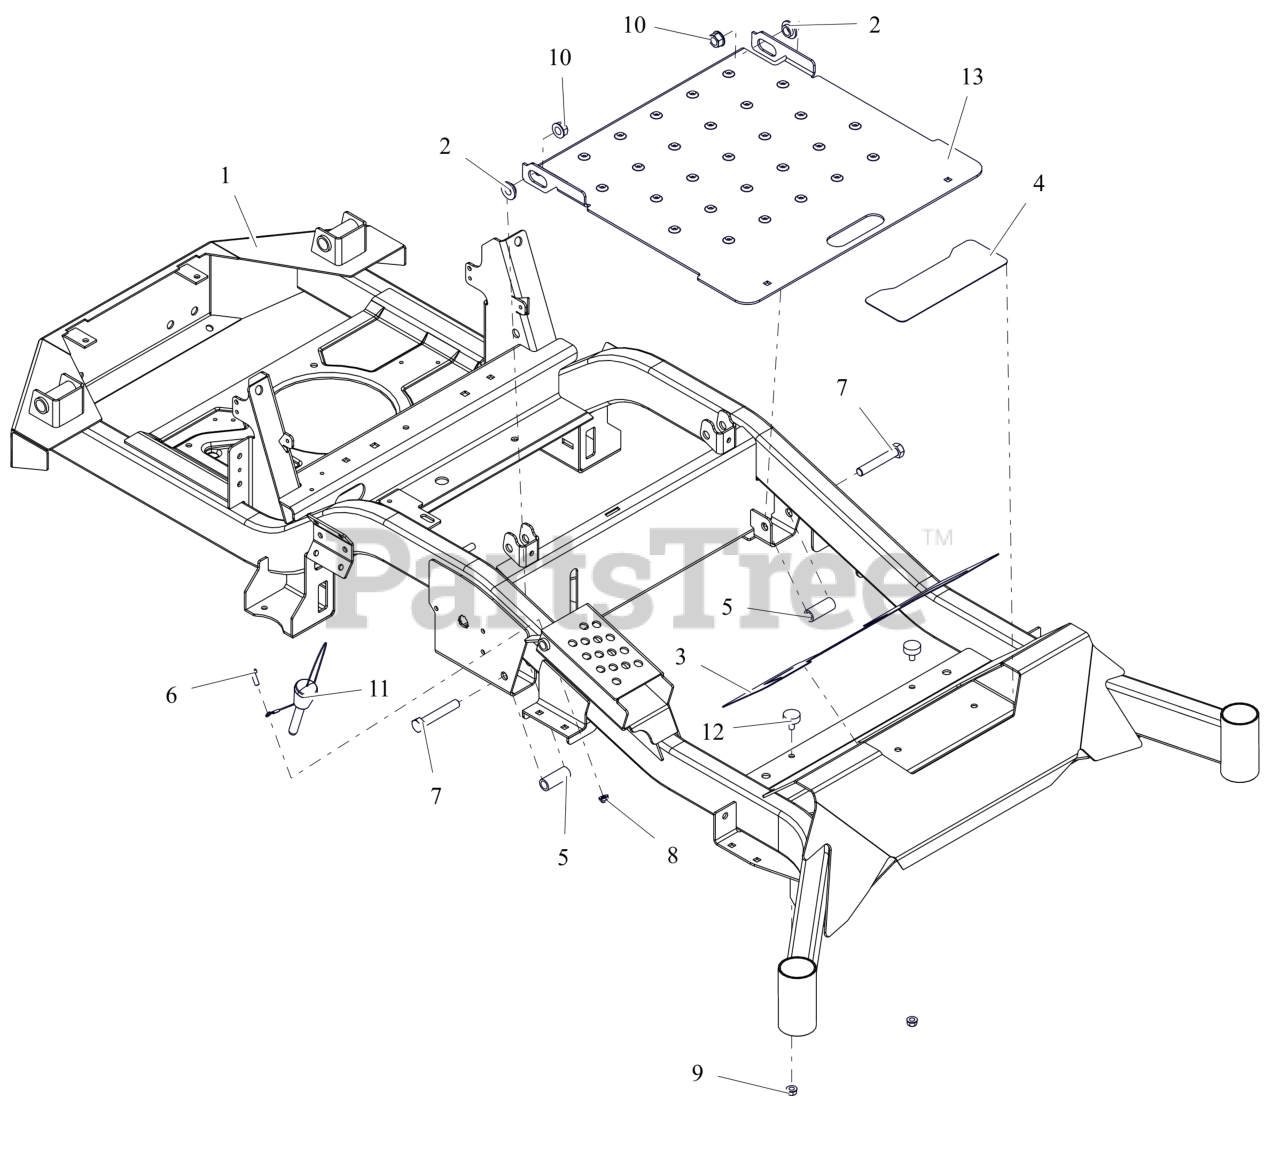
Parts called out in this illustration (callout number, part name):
1	WLDMT, MAIN FRAME - APEX 60
2	BSHG-FLG .515X.750X.395X1.120
3	GRIP, FRONT
4	GRIP, STEP
5	SPACER, .515X.75X1.83
6	BLT, HEX .25-20X.75 G5 ZCC
7	BLT, HEX .50-13X3.00 G5 ZCC
8	NUT,NYL-FLG .25-20 GF ZCC
9	NUT,SPNLK-FLG .31-18 G5 ZCC
10	NUT-LK-TOP-FLG .500-13 GF ZCC
11	PIN, MAGNETIC .50X2.50
12	BUMPER, RUBBER
13	PANEL, ACCESS
